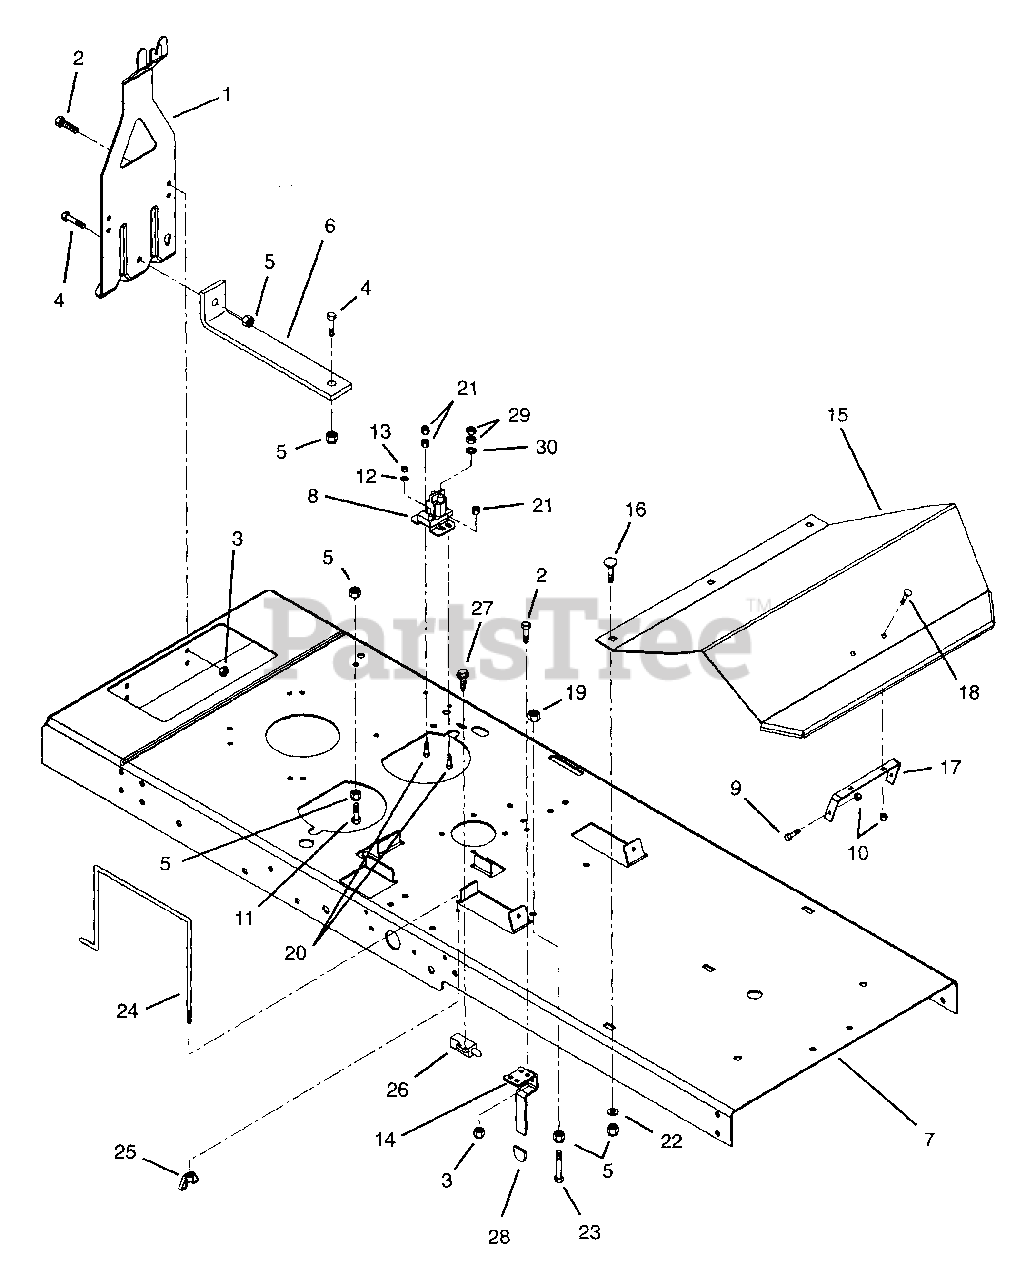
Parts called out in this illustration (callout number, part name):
1	HITCH,TRAILER
2	BLT-HEX .31-18X.75 PL GR5
3	NUT-LK .312-18 GR A PL
4	BLT-HEX .38-16X1.00 PL GR5
5	NUT-LK-CTR .375-16 GR A PL
8	SOLENOID
9	BLT-HEX .25-20X.75 PL GR5
10	NUT-LK-NYL .250-20 PL
11	BLT-HEX .38-16X2.00 PL GR5
12	WSHR-LK-EXT #10 ID X .022
13	NUT 10-32 PL
14	CLUTCH STOP
15	FOOTREST
16	BLT-RDHDSQNK .38-16X1.0 GR5PL
17	BRACKET, FOOTREST
18	BLT-RDHDSQNK .25-20X.75 GR5PL
19	NUT-HEX .375-16
20	BLT-HEX .25-20X.75 PL GR5
21	NUT-LK-NYL .250-20 PL
22	WHSR-FL-.380X.875X.160
23	BLT-HEX .38-16X5.00
24	BATTERY ROD
25	NUT-LK WING .250-20
26	SWITCH- SINGLE POLE N.O.
27	SCR-TAP 12-24X.50 HWH PL TR
29	NUT-JAM .312-24 PL
30	WSHR-LK-INT .313X.030 PL
